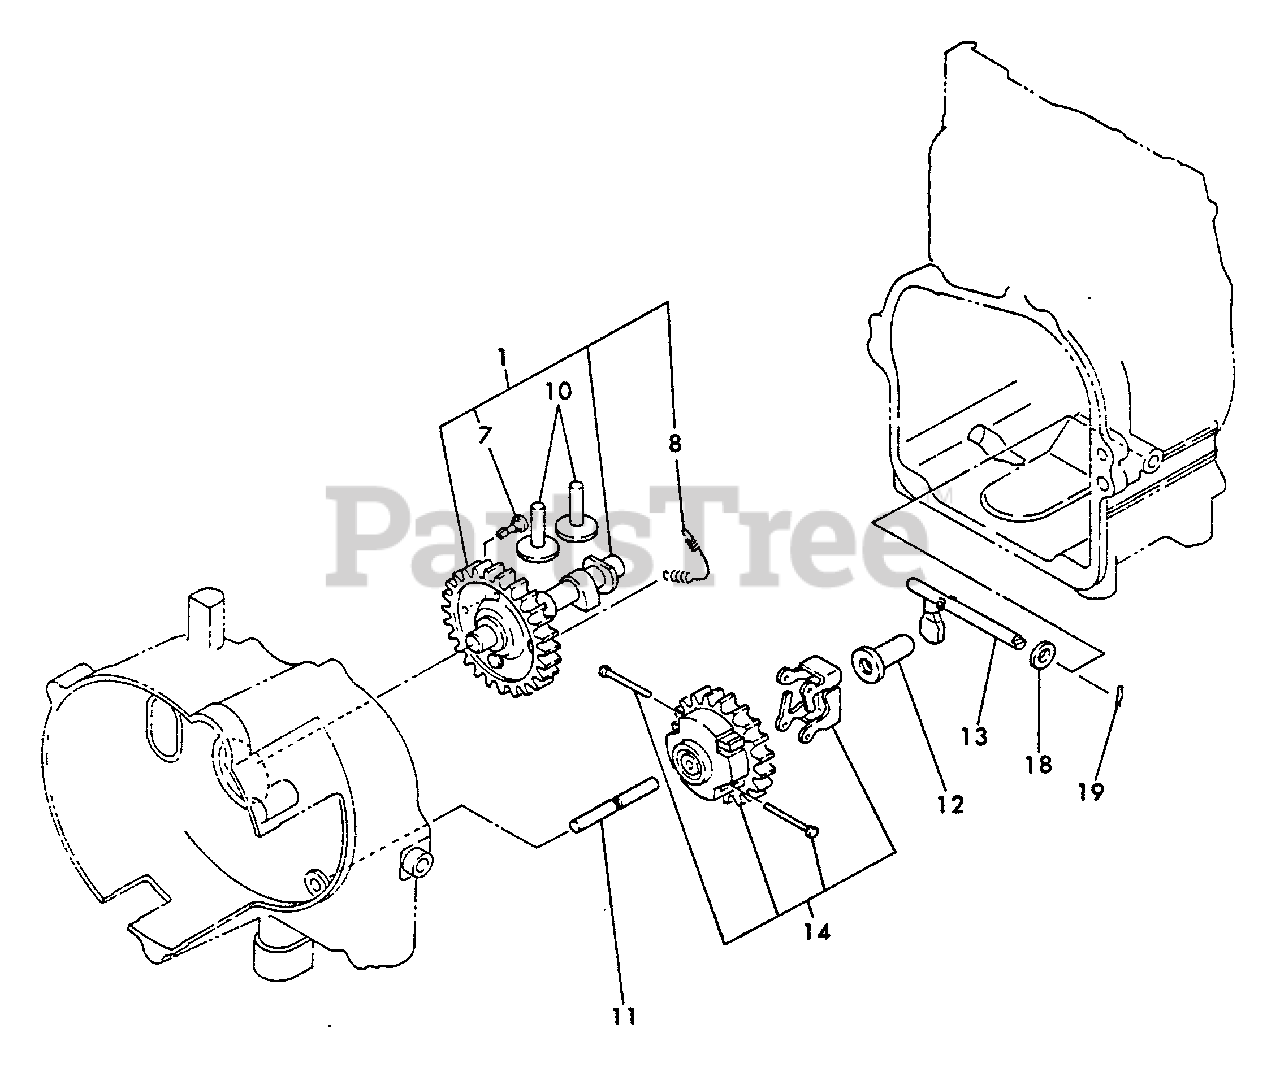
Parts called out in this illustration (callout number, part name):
1	CAMSHAFT ASSY
7	PIN
8	SPRING
10	TAPPET
11	SHAFT, GOVERNOR
12	SPINDLE, GOVERNOR
13	SHAFT, GOV. LEVER
14	GOVERNOR GEAR ASSY
18	WASHER - 6
19	PIN - 6 -- SNAP
